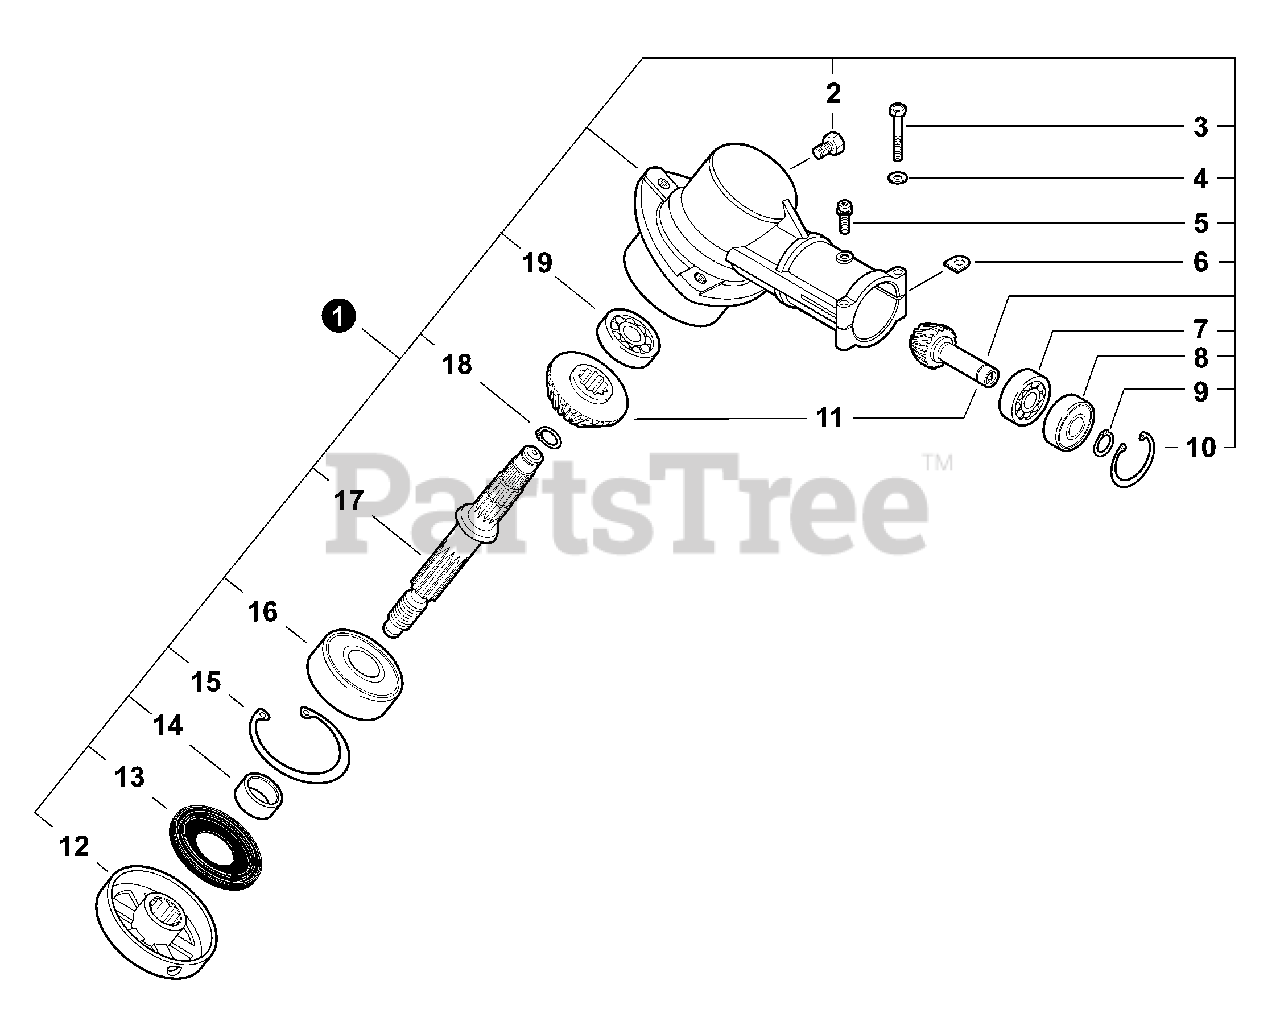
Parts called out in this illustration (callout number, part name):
1	GEAR CASE ASSY
2	BOLT M8×8
3	BOLT 5×35 SP
4	WASHER, FLAT 5.5×10×0.8
5	SCREW 5×10
7	BEARING, BALL 6900
8	BEARING, BALL 6900Z
9	RING, SNAP Ø10
10	RING, SNAP Ø22
11	GEAR SET
12	PLATE, ADAPTOR - UPPER
13	SEAL, OIL 22
14	SPACER 11.8×15×9
15	RING, SNAP Ø32
16	BEARING, BALL 6201
17	SHAFT, GEAR
18	RING, SNAP Ø12
19	BEARING, BALL 609
